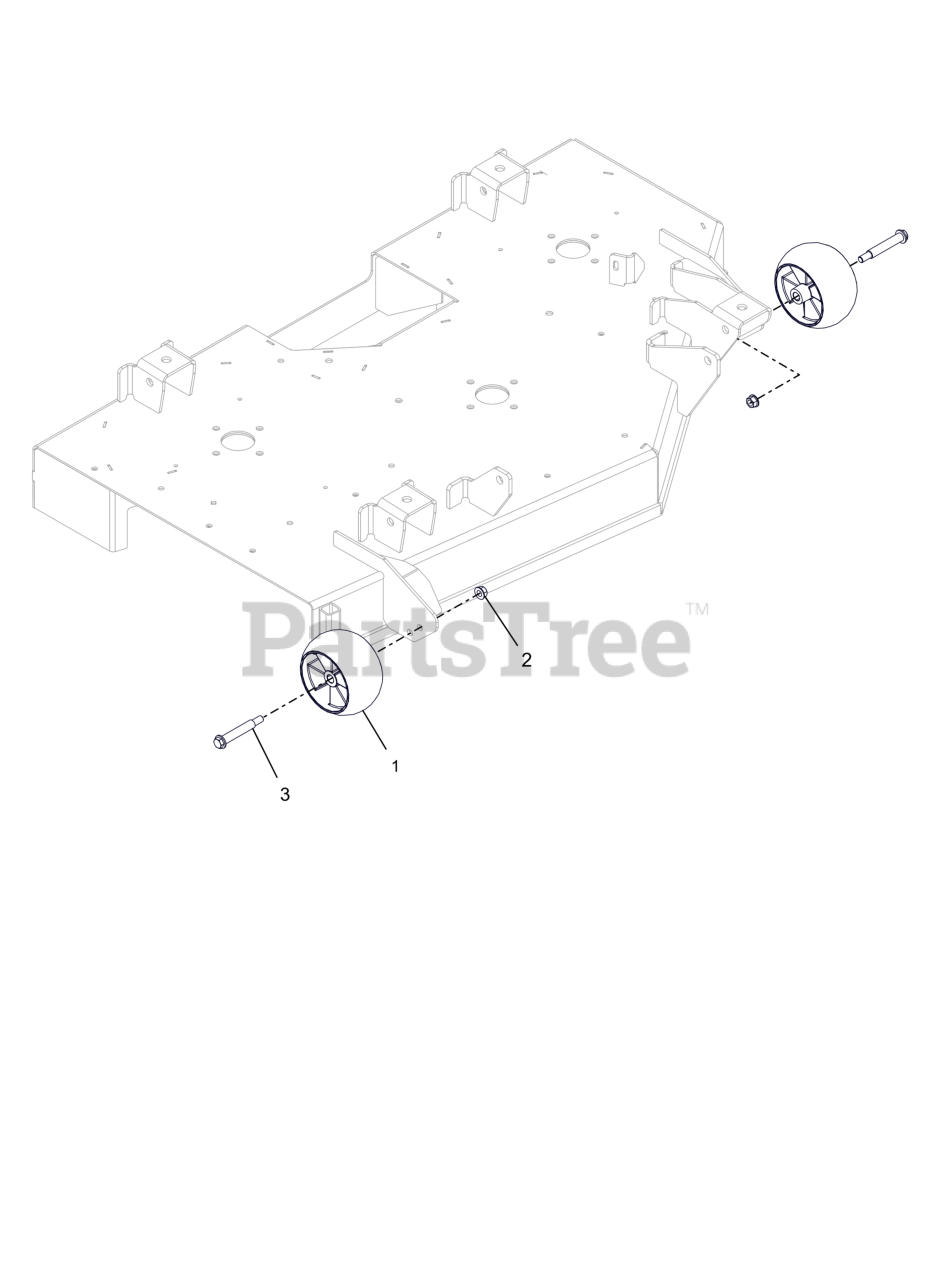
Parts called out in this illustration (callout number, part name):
1	ANTI-SCALP WHEEL - 5X OS
2	NUT-LK-TOP-FLG .38-16 ZC120
3	BLT-SHLDR .38-16X2.50 HWH G5
